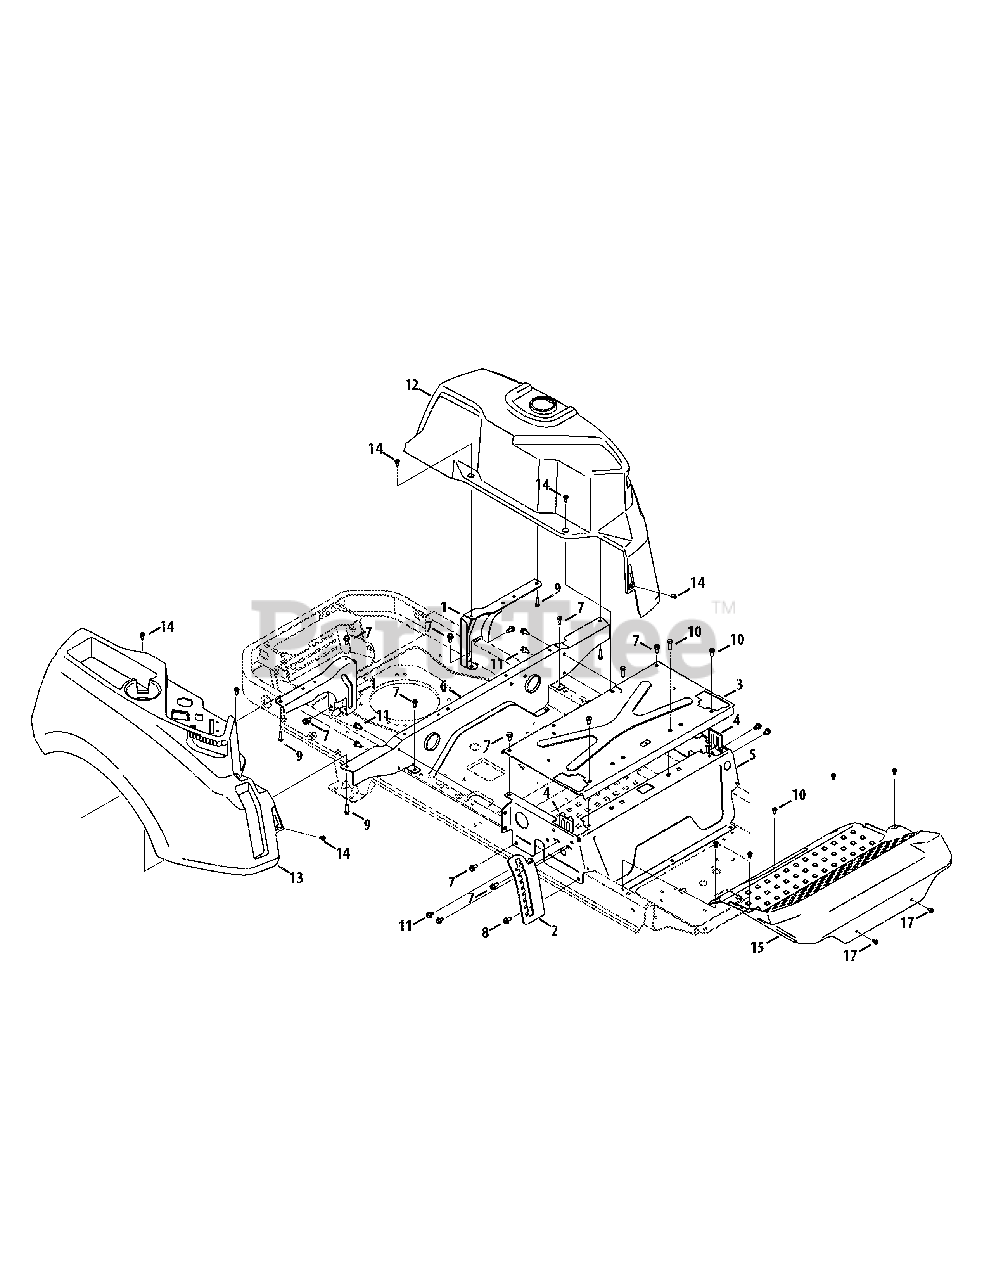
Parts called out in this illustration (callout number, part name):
1	Rear Tank Bracket
2	Height Index Bracket
3	Lap Bar Bracket Brace
4	Rear Seatbox Brace
5	Hex Washer Screw, 5/16-18 x .750
6	Hex Washer Screw, 5/16-18 x .750
7	Hex Washer Screw, 3/8-16 x 1.000
8	Hex Washer Screw, 5/16-14 x 1.00
9	Screw, 5/16-18 x .750
10	Hex Washer Screw, 5/16-18 x .500
11	Hex Washer Screw, 5/16-18 x .500
12	LH Console
13	RH Console
14	Shoulder Screw, 1/4-20
15	Floor Board
16	Screw, 1/4-20 x .5
17	Screw, 5/16-18 x .750
